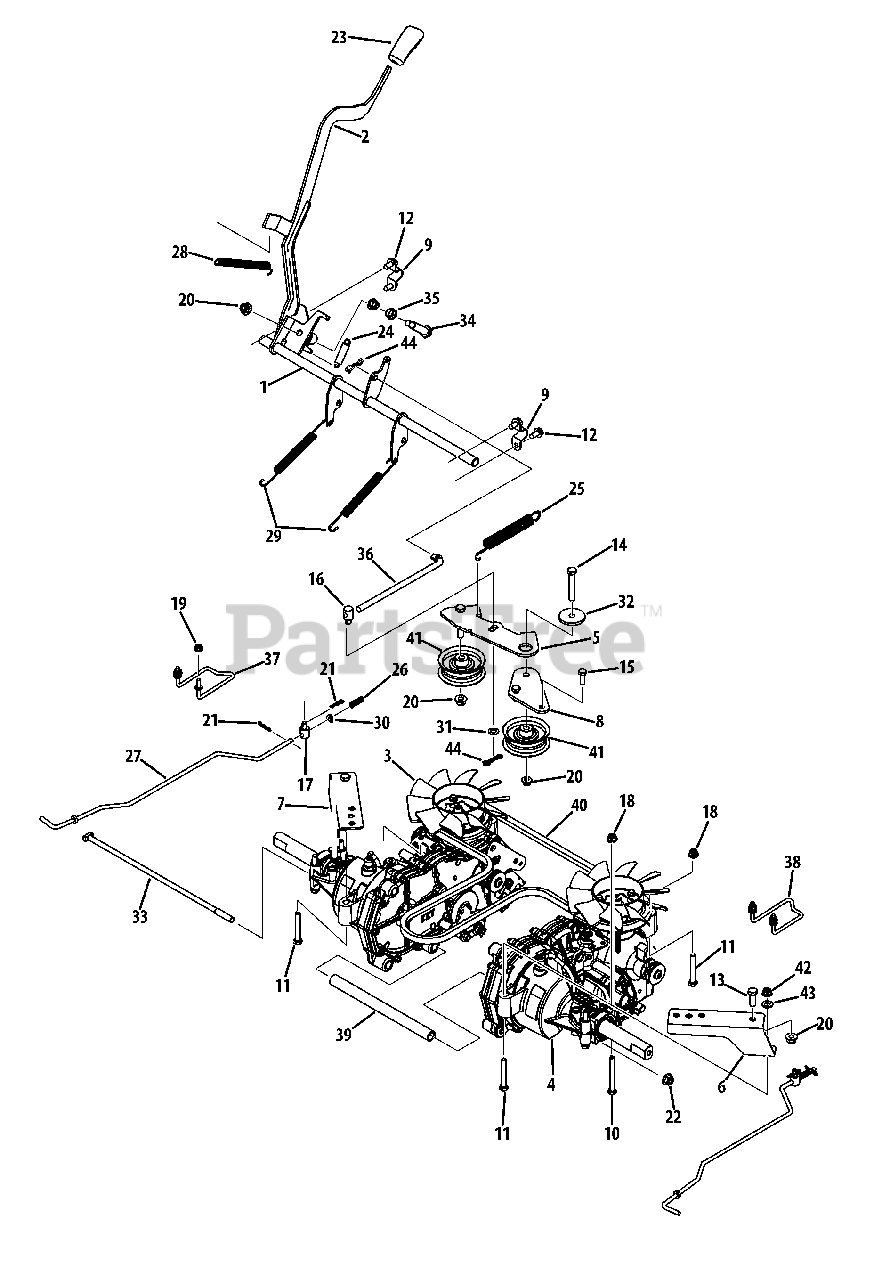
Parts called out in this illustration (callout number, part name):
1	Brake Shaft Assembly
2	Brake Handle Assembly
3	LH Transmission Assembly
4	RH Transmission Assembly
5	Idler Bracket
6	RH Mount Bracket
7	LH Mount Bracket
8	Idler Mount Plate
9	Shaft Mount Bracket
10	Hex Screw, 5/16-18 x 2.75
11	Hex Screw, 5/16-18 x 2.25
12	Hex Washer Screw, 5/16-18 x .750
13	Hex Screw, 3/8-16 x 1.00
14	Hex Screw, 3/8-16 x 2.25
15	Hex Screw, 5/16-18 x .875
16	Ferrule, 3/8-24 x .375
17	Ferrule, .325 x .312
18	Flange Lock Nut, 5/16-18
19	Flange Lock Nut, 1/4-20
20	Flange Lock Nut, 3/8-16
21	Cotter Pin, .072 x 1.13
22	Flange Lock Nut, 7/16-20
23	Selector Handle
24	Extension Spring, .48 x 2.03
25	Extension Spring, .75 x 6.02
26	Compression Spring, .34 x 1.0
27	Transmission Bypass Lever Wire
28	Extension Spring, .50 x 6.37
29	Extension Spring, .500 x 7.0
30	Spring Washer, .317 x .625 x .020
31	Thrust Washer, .375 x .70 x .030
32	Shoulder Spacer, .884 x .190
33	Rod, .405 x 14.00
34	Shoulder Screw, .498 x 1.635
35	Flange Bearing, .500 x .34
36	Disengage Brake Rod
37	LH Keeper Rod
38	RH Keeper Rod
39	Transmission Spacer, 9.40
41	Flat Idler Pulley, 2.75
42	Hex Lock Nut, 5/16-24
43	Flat Washer, .330 x .630 x .064
44	Bow-Tie Cotter Pin
